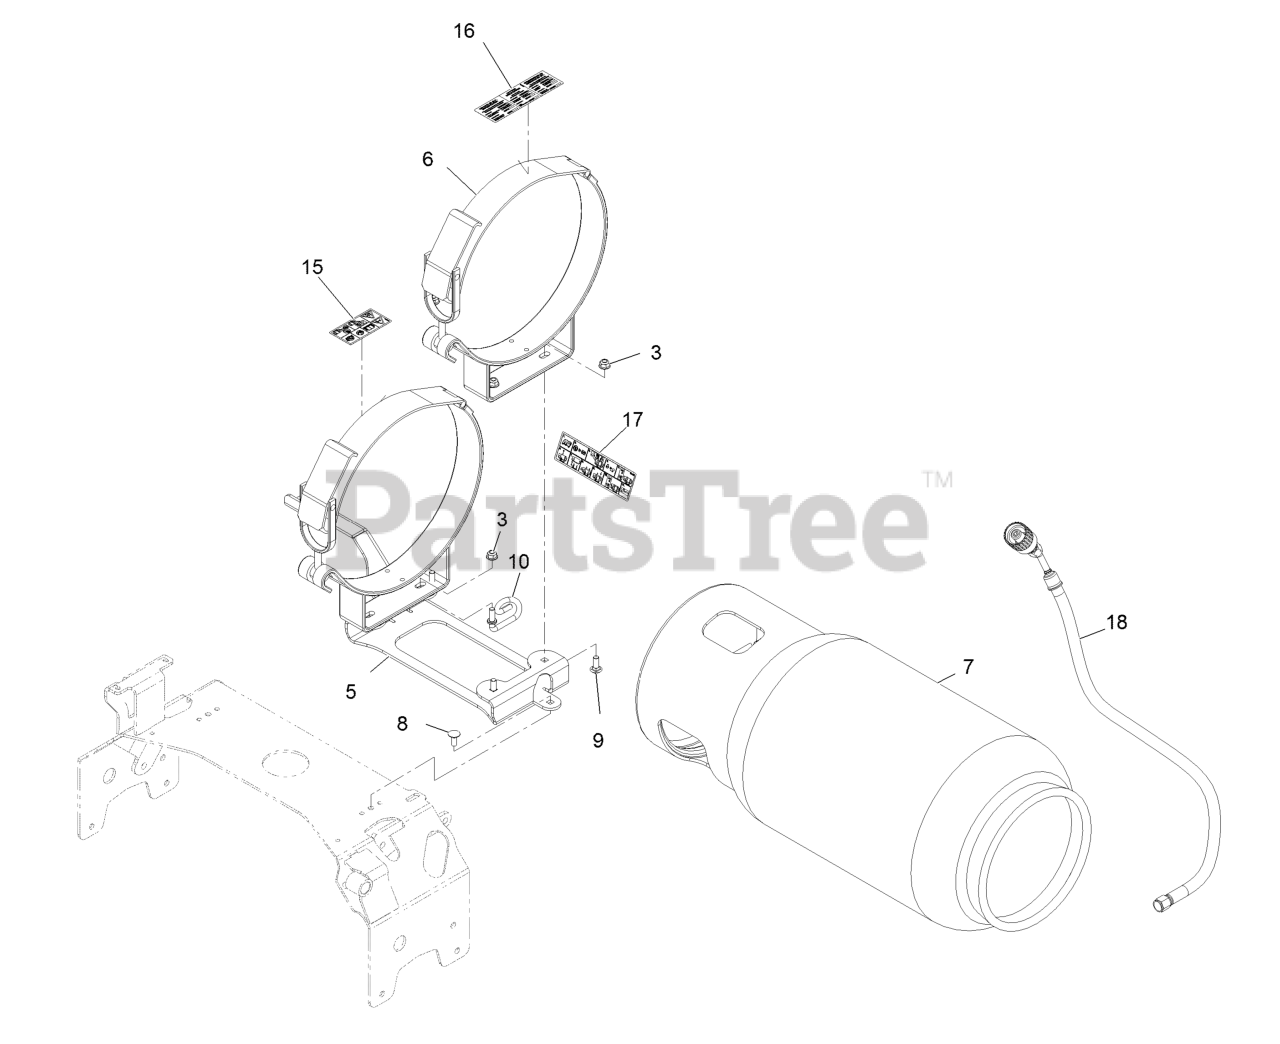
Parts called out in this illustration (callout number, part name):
3	Nut-Nyloc 5/16-18 Flg
5	Weld, Tank Mount
6	Brackets, LPG Tank - Horizontal (Pair)
7	Tank, LP - 33.5 Lb.Horizontal-Al
8	Bolt-Carriage 5/16-18 X 3/4 Short Neck
9	Bolt-Carriage 5/16-18 X 7/8
10	Retainer, LP Hose
15	Decal-LPG Warning
16	Decal-LPG Horiz Tank Spec
17	Decal-LPG Fuel Tank Replacement
18	ASM, LPG Hose W/Connector-Tt
